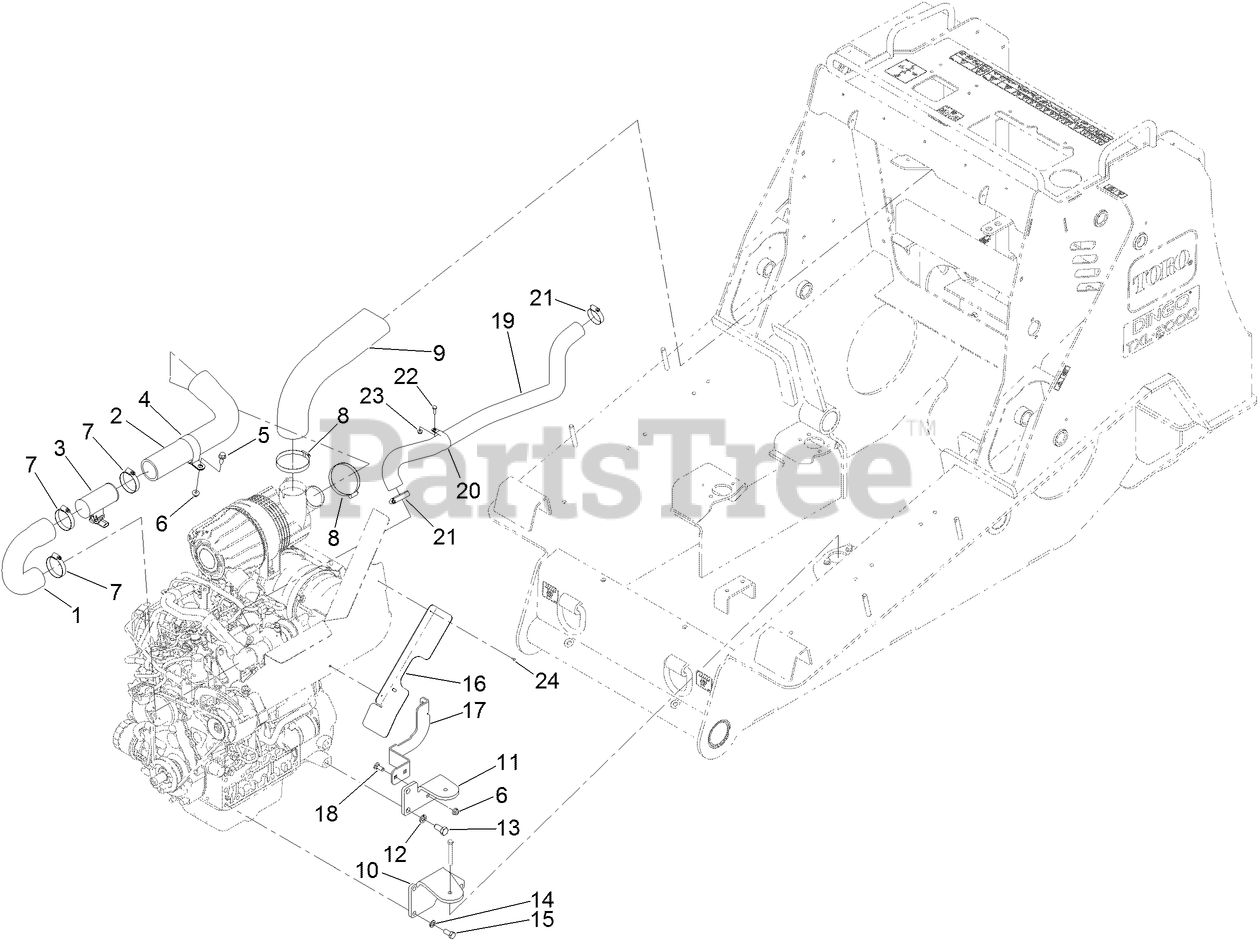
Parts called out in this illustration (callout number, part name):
1	HOSE-INTAKE
2	HOSE-INTAKE, AIR
3	SENSOR
4	CLAMP-R
5	SCREW-HHF
6	NUT-HF, NI
7	CLAMP-HOSE
8	CLAMP-BAND/SCREW
9	HOSE-INTAKE
10	MOUNT-ENGINE
11	MOUNT-ENGINE
12	WASHER-LOCK, SPRING
13	SCREW-HH
14	WASHER-LOCK
15	SCREW-HH
16	SHIELD-STARTER
17	BRACKET-PUMP, LH
18	BOLT-CARR
19	HOSE-AIR, COOLER
20	CLAMP-R
21	CLAMP-HOSE
22	SCREW-HH
23	NUT-HF
24	RIVET-POP
